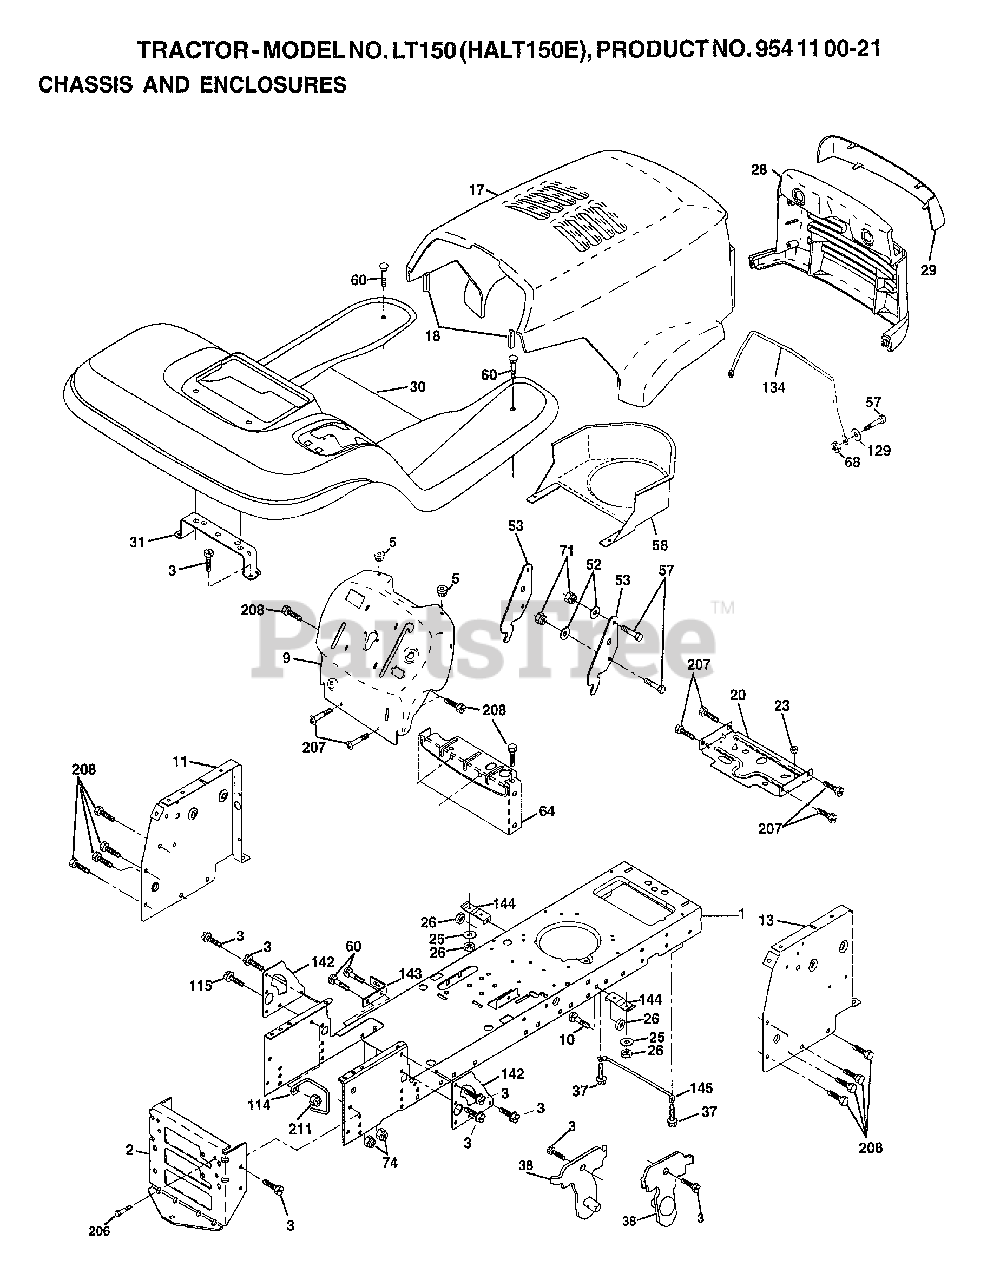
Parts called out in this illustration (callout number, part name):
1	CHASSIS STAMPING
2	DRAWBAR
9	DASH
10	BOLT CARRIAGE 3/8-16X1
17	HOOD
18	"BUMPER,HOOD T"
25	WASHER
26	LOCKNUT
28	GRILLE
29	LENS
30	FENDER FOOTREST
37	SCREW, 5/16-18 X 1/2 HEX, SELF TAPPING
38	BRK ASM
51	NUT LOCK HEX W/INS 1/4-20
52	WASHER 9/32 X 7/8 X 16 GA
57	BOLT HEX 1/4-20 X 3/4
68	LOCKNUT
71	NUT CROWNLOCK 1/4-20
74	NUT, CROWNLOCK 3/8-16
114	KEEPER BELT REAR
129	WASHER 9/32 X 5/8 X 16 GA.
134	"ROD-SUPPORT,HOOD"
142	PLATE.REINFORCEMENT
206	BOLT SHOULDER
